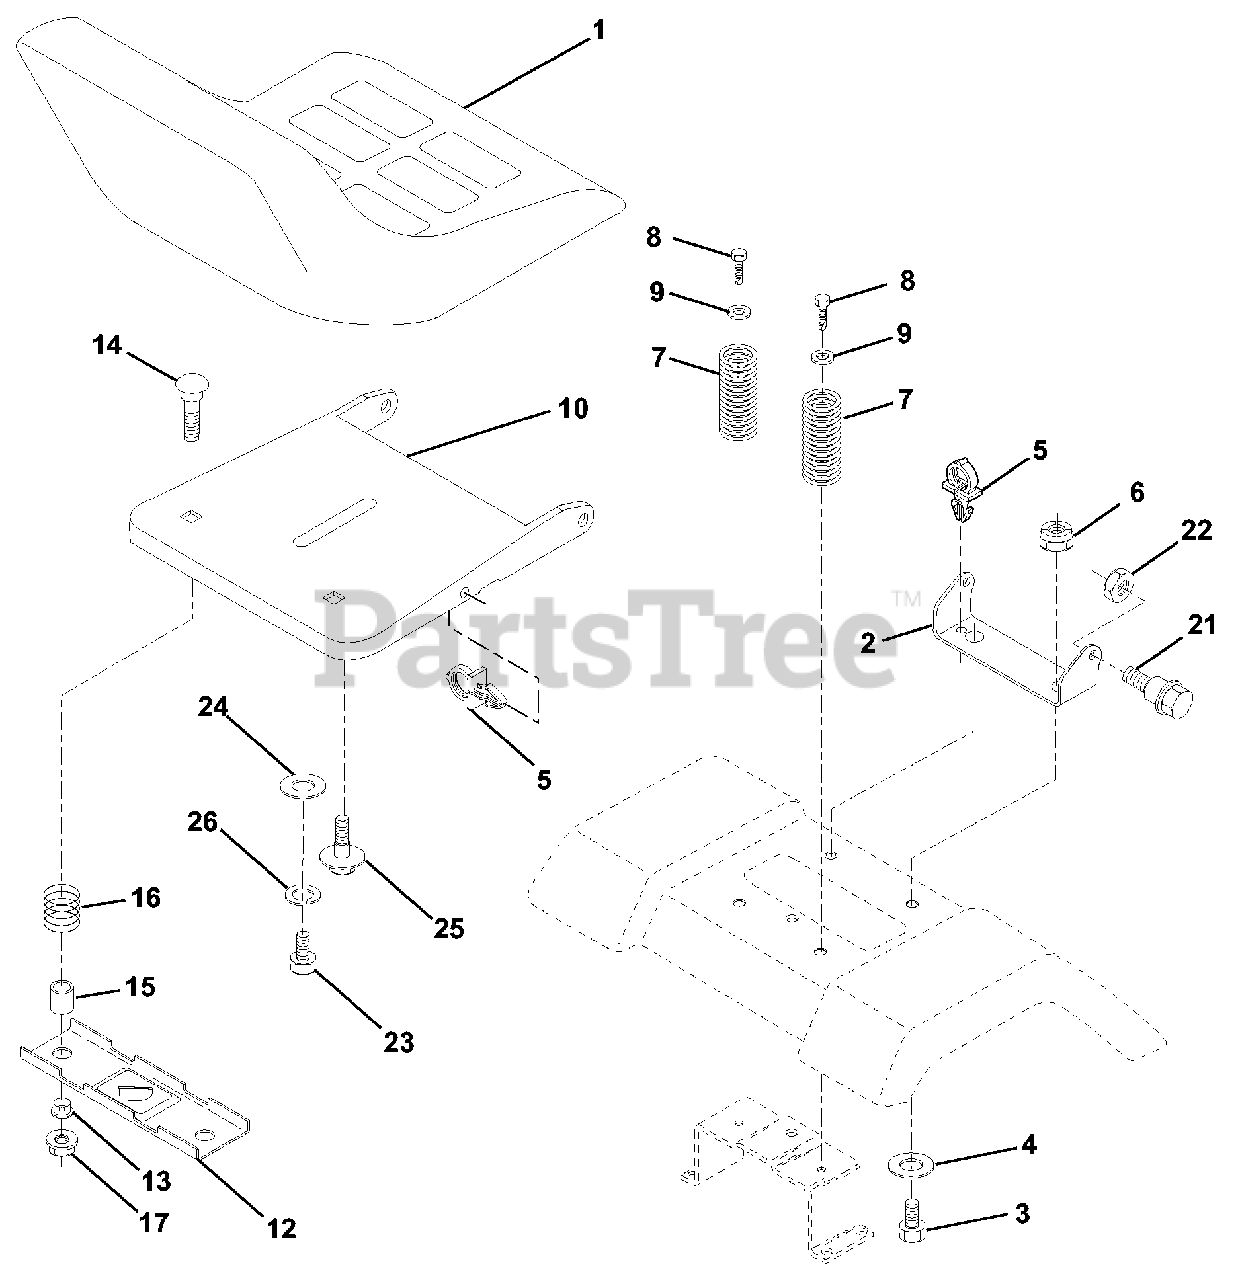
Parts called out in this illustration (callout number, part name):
1	Seat
2	Bracket Pivot Seat 8 720
3	Bolt Fin Hex 3/8-16unc X 1
4	Washer 13/32 X 1 X 10 Ga
5	Clip Push-In
6	Nut Hex w/Ins. 3/8-16 Unc
7	Spring Seat Cprsn 2 250 Blk Zi
8	Screw Thdrol 3/8-16 X 1 Ty-tt
9	Washer 13/32 X 1 X 14 Ga.
10	Pan Seat
12	Bracket Mounting Switch
13	Bushing Snap Blk Nyl 50 Id
14	Bolt Rdhd Sqnk 1/4-20x1-3/8
15	Spacer Split 28x 96 Yel Zinc
16	Spring Cprsn 1 27 Blk Pnt
17	Nut Lock 1/4 Lge Flg Gr 5 Zinc
21	Bolt Shoulder 5/16-18 Unc
22	Nut Hex Lock W/Ins 5/16-18
23	Bolt, Hex Head, Fin 1/2-13 x 7/8 Grade 5
24	Washer 17/32 X 1-3/16 X 12 Ga.
25	Bolt Shoulder 5/16-18 X 62
26	Washer Lock
